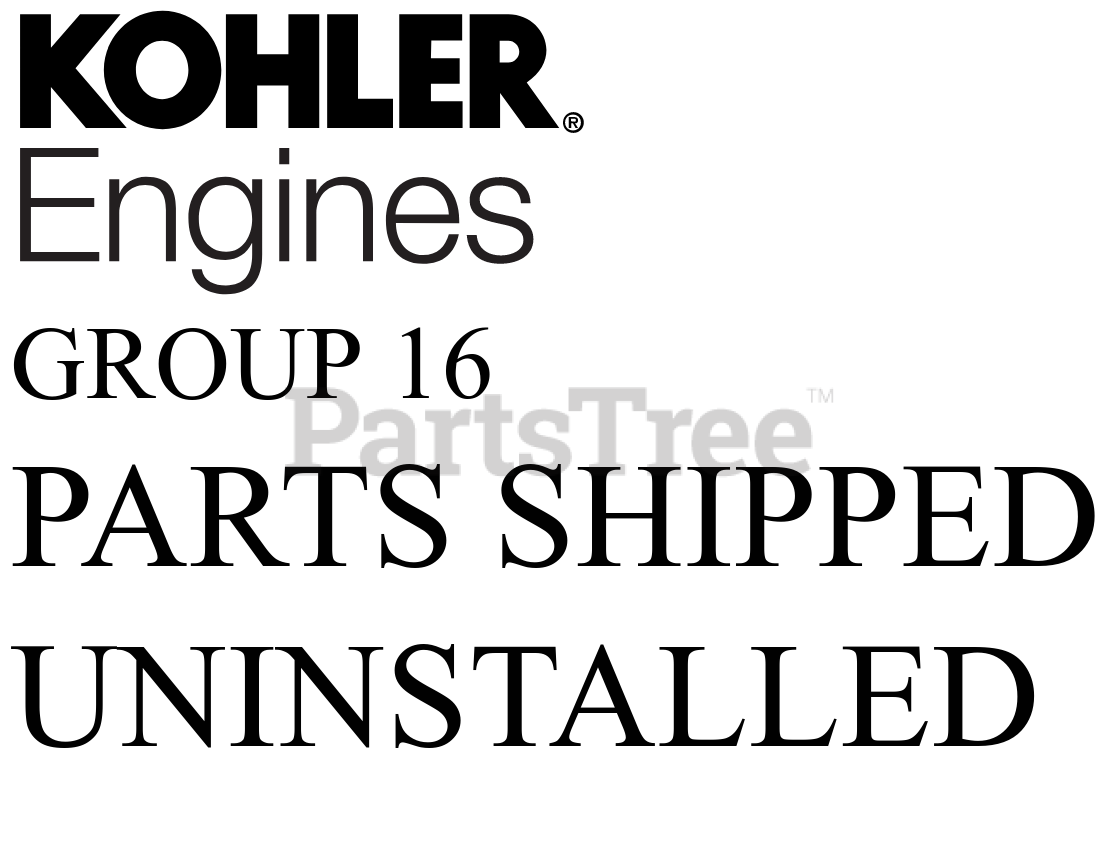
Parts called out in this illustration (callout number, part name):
NI	KEY ASSEMBLY SWITCH-USE 25 099 37-S
NI	HARNESS, WIRING
NI	SENSOR, OXYGEN (M18 x 1.5 THREADS)
